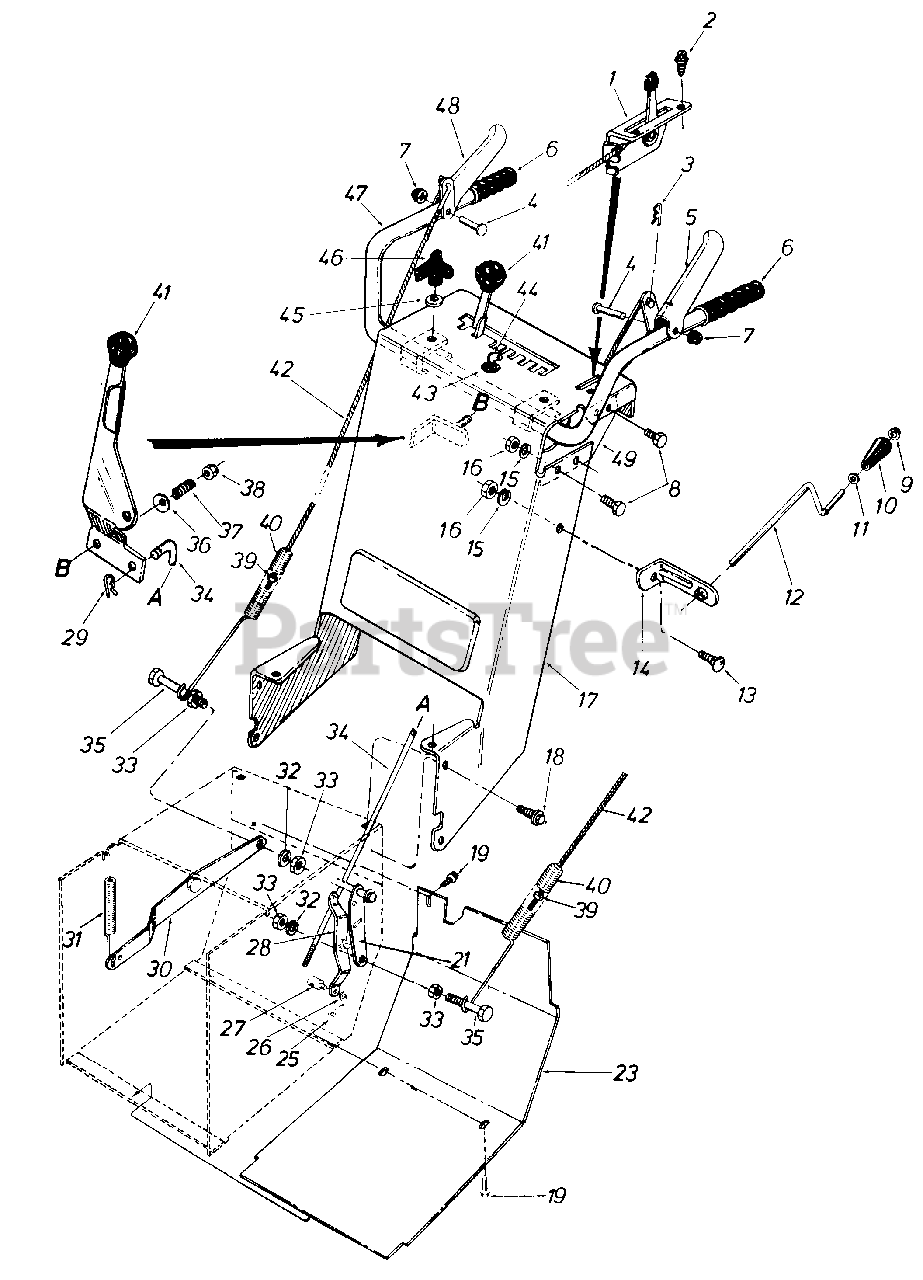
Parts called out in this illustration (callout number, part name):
1	Throttle Control Ass'y. Comp.
2	Hex Wash. Hd. AB-Tap Scr. #8 x .50
3	Hairpin Cotter 3/32" Dia. x 1.00" Lg.
4	Clevis Pin .375" Dia. x 1.88" Lg.
5	Drive Clutch Grip Ass'y. - L.H.
6	Grip Handle
7	Push Cap for 3/8" Rod
8	Hex Bolt 5/16-24 x .62" Lg.
9	Push Nut for 3/8" Rod
10	Knob w/.38" Dia. Hole
11	Fl. Wash. .385" I.D. x .62" O.D. x .063"
12	Chute Crank .38 Dia. x 35" Lg.
13	Carriage Bolt 5/16-18 x .62" Lg.
14	Chute Control Brkt.
15	L-Wash. 5/16"
16	Hex Nut 5/16-24 Thd.
17	Handle Panel Ass'y.
18	Hex Wash. Self-Tap Scr. 5/16-24 x .50" Lg.
19	Hex Wash. Self-Tap Scr. 5/16-24 x .50 Lg.
21	Drive Clutch Brkt. Ass'y.
23	Frame Cover
25	Cotter Pin 3/32" Dia. x .75" Lg.
26	Fl. Wash. .344" I.D. x .62" O.D. x .063
27	Ferrule - Engagement
28	Shifting Linkage Brkt.
29	Hairpin Cotter 3/32" Dia. x 1.00" Lg.
30	Auger Clutch Brkt.
31	Ext. Spring .38" O.D. x 3.18" Lg.
32	L-Wash. 1/4" I.D.
33	Hex Nut 1/4-28 Thd.
34	Shifting Rod
35	Hex Bolt 1/4-28 x 1.75" Lg.
36	Bell-Wash. .400 I.D. x .88 O.D. x .060
37	Comp. Spring .39 I.D. x .88
38	Hex Ins. L-Nut 3/8-24 Thd.
39	Hex Ins. L-Nut 1/4-20 Thd.
40	Spring .75" O.D. x 5.0" Lg.
41	Shift Handle Ass'y.
42	Lock-Out Cable 30.5" Lg.
43	Ignition Switch
44	Ignition Key
45	Bell-Wash. .345 I.D. x .88 O.D. x .060
46	Three Arm Knob - 5/16-18 Thd.
47	Handle Ass'y.
48	Auger Clutch Grip Ass'y. - R.H.
49	Handle Support Brkt.
